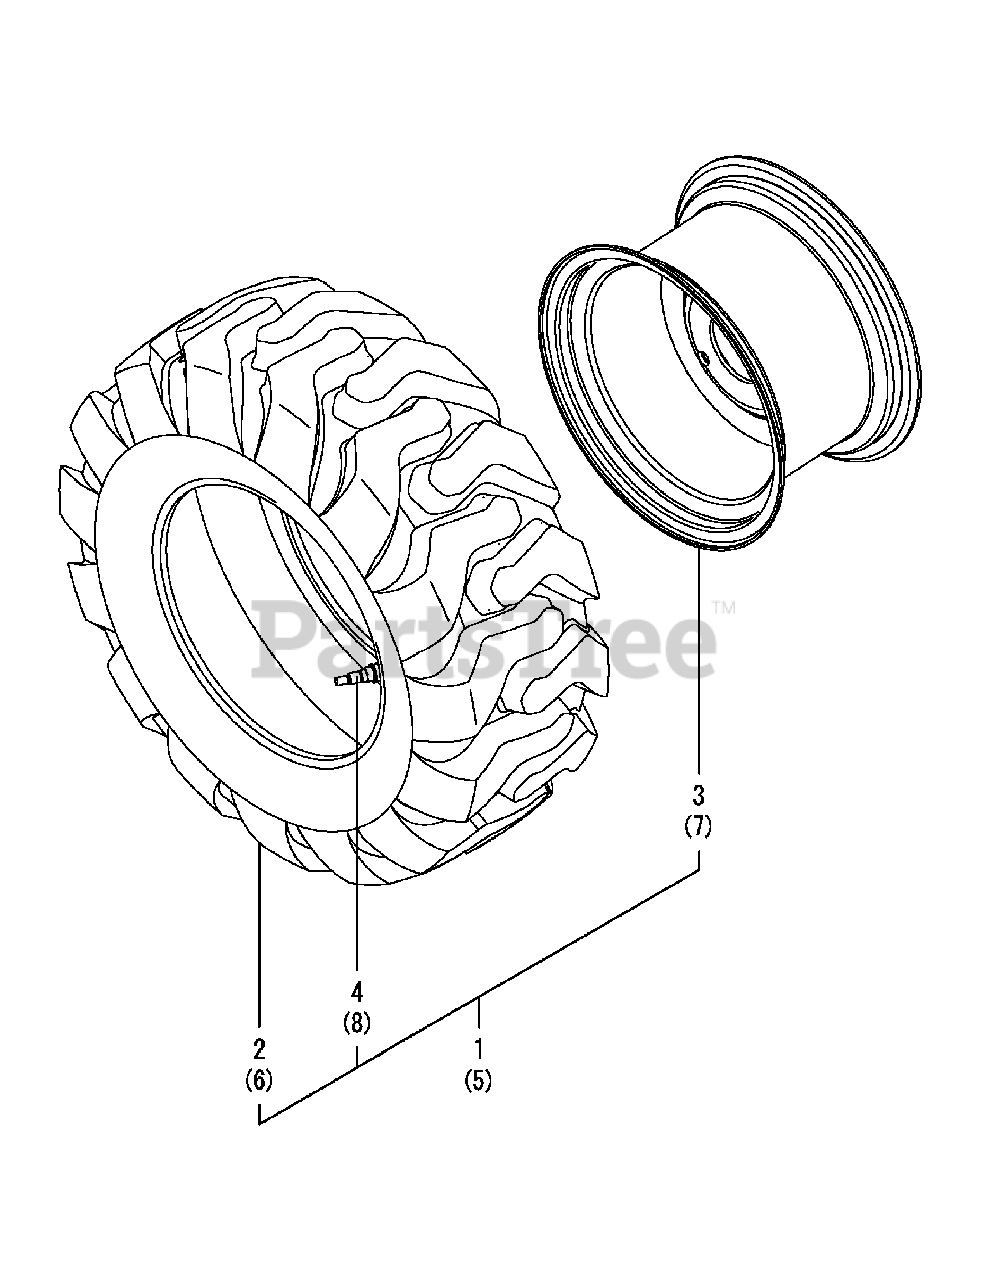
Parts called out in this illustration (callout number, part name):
1	Tire Assembly, Front L R4
2	Tire, 23X8.5-12 R4
5	Tire Assembly, Front R R4
6	Tire, 23X8.5-12 R4
